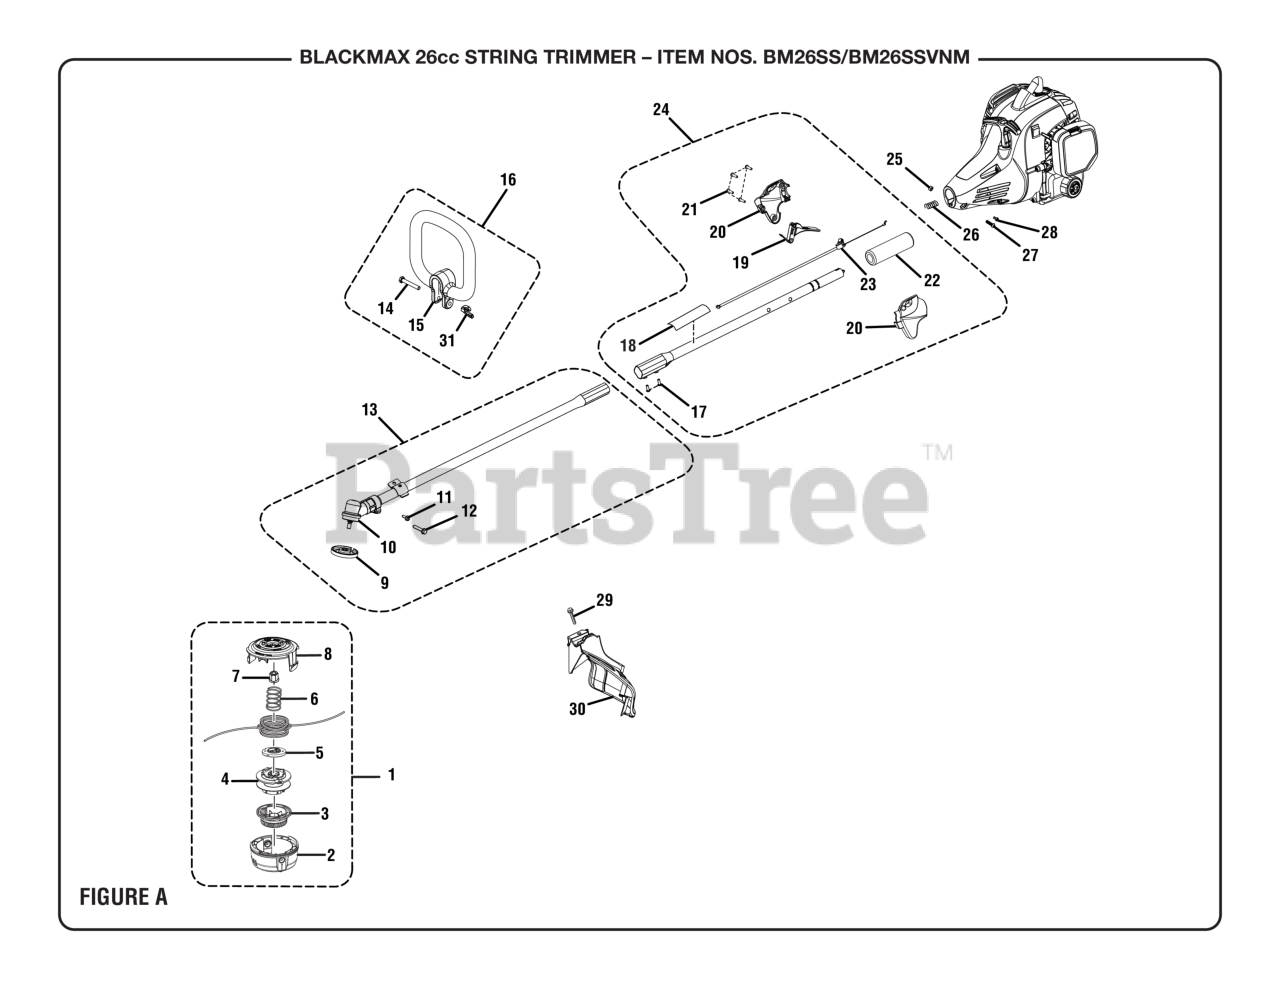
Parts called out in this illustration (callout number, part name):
1	Trimmer Head Assembly
2	Lower Housing
3	Bump Knob (Gray)
4	Spool Assembly
5	String Guide
6	Compression Spring
7	Hex Nut (M8, Left Hand Threads)
8	Upper Housing
9	FLANGED WASHER
10	Gear Head
11	Screw w/Washer (10-24 x 5/8 in., Hex Hd. T.F.)
12	Screw (1/4-20 x 1-1/4 in., Hex Washer Hd. S.T.)
13	Lower Boom Assembly
14	Bolt (1/4-20 x 45 mm, Cap Hex Hd.)
15	Front Handle
16	Front Handle Assembly
17	Set Screw (M5 x 10 mm, Hex Soc. Hd.)
18	Icon Warning Label
19	Throttle Trigger
20	Handle Assembly (Inc. Key Nos. 19 & 21)
21	Screw (M4 x 20 mm, T20 Torx Pan Hd. T.Fl.)
22	Rubber Grip
23	Throttle Cable
24	Boom Assembly (Inc. Key Nos. 17-23)
25	Hex Nut (M6.3 x 1)
26	Compression Spring
27	Screw (M6 x 20 mm, T27 Torx Button Hd.)
28	Screw (M4 x 8 mm, T25 Torx Pan Hd. T.F.)
29	SCREW (#1/4-20 X 1-1/4 in. HEX WASHER HD.)
30	Grass Deflector Assembly
31	Wing Nut (1/4-20, Plastic)
